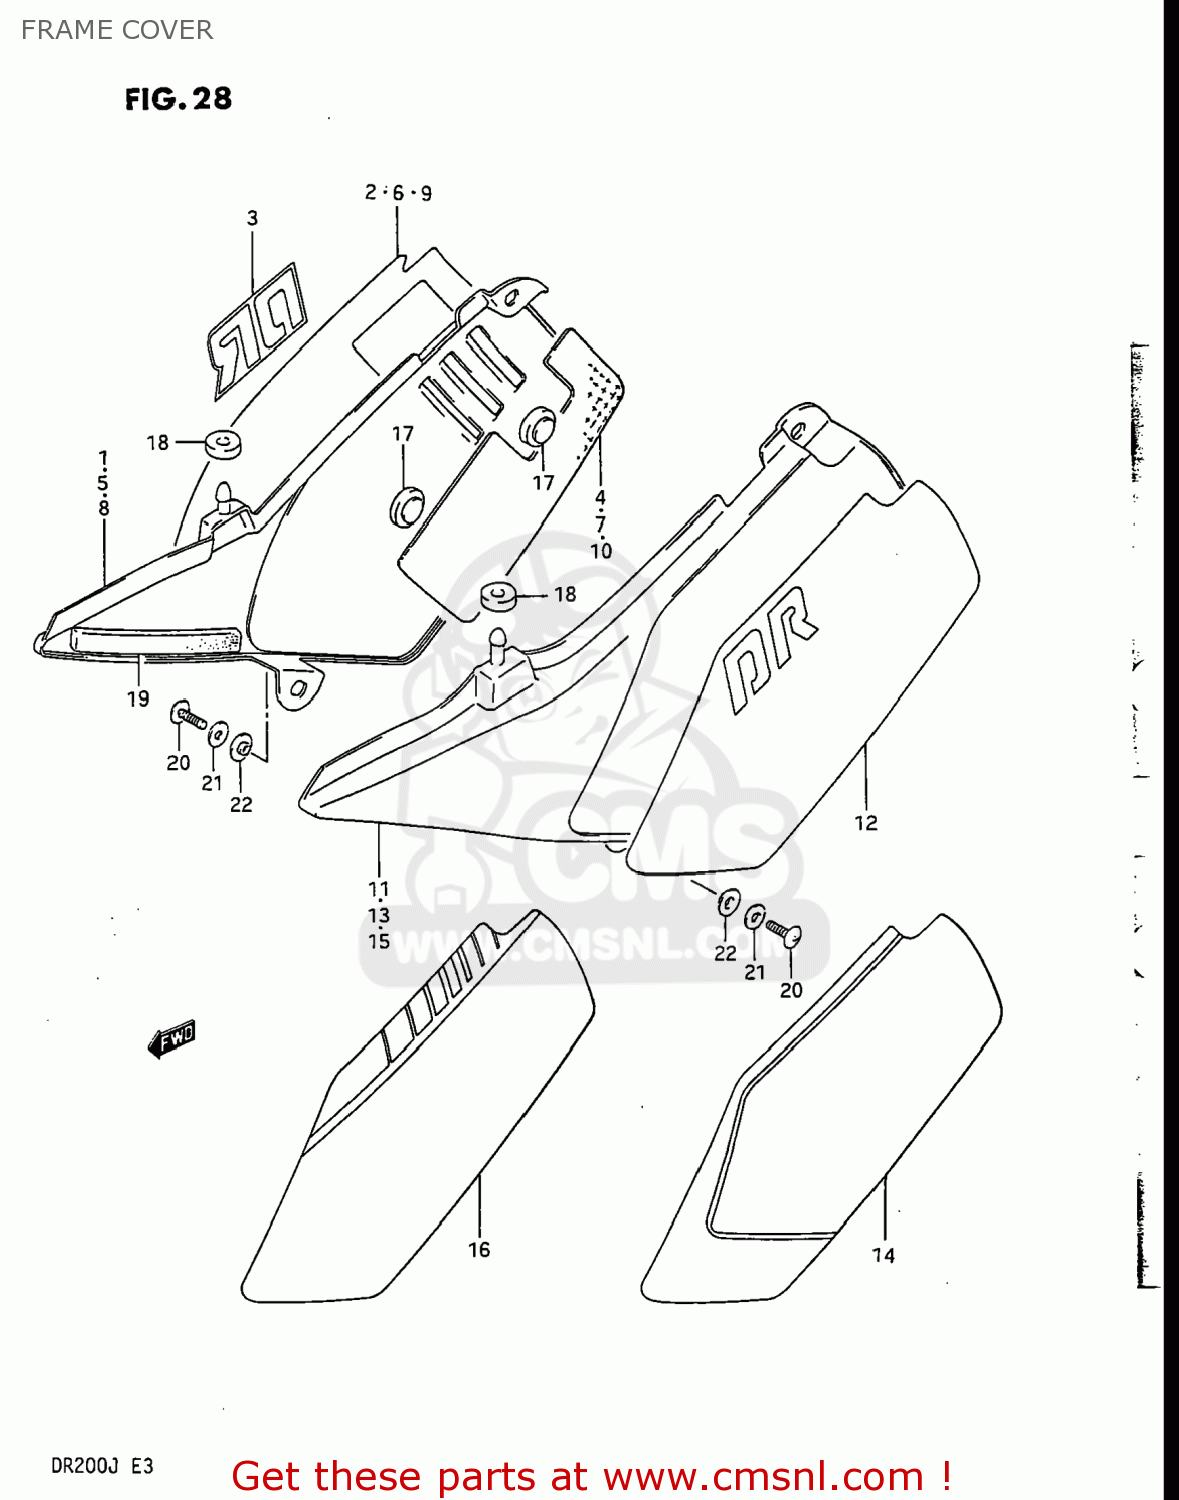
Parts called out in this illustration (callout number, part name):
1	COVER,FRAME,RIGHT
2	TAPE SET,FRAME COVER,RIGHT
3	EMBLEM,RIGHT
4	SHIELD,FRAME COVER,RIGHT
5	COVER,FRAME,RIGHT
6	TAPE SET,FRAME COVER,RIGHT
7	SHIELD,FRAME COVER,RIGHT
8	COVER COMP,FRAME,RIGHT
9	TAPE,FRAME COVER,RIGHT
10	SHIELD,FRAME COVER,RIGHT
11	COVER,FRAME,LEFT
12	TAPE SET,FRAME COVER,LEFT
13	COVER,FRAME,LEFT
14	TAPE SET,FRAME COVER,LEFT
15	COVER COMP,FRAME,LEFT
16	TAPE,FRAME COVER,LEFT
17	CUSHION
18	CUSHION,SIDE COVER BOSS
19	CUSHION,FRAME COVER
20	SCREW
21	WASHER (6.5X18X1.6)
22	WASHER
